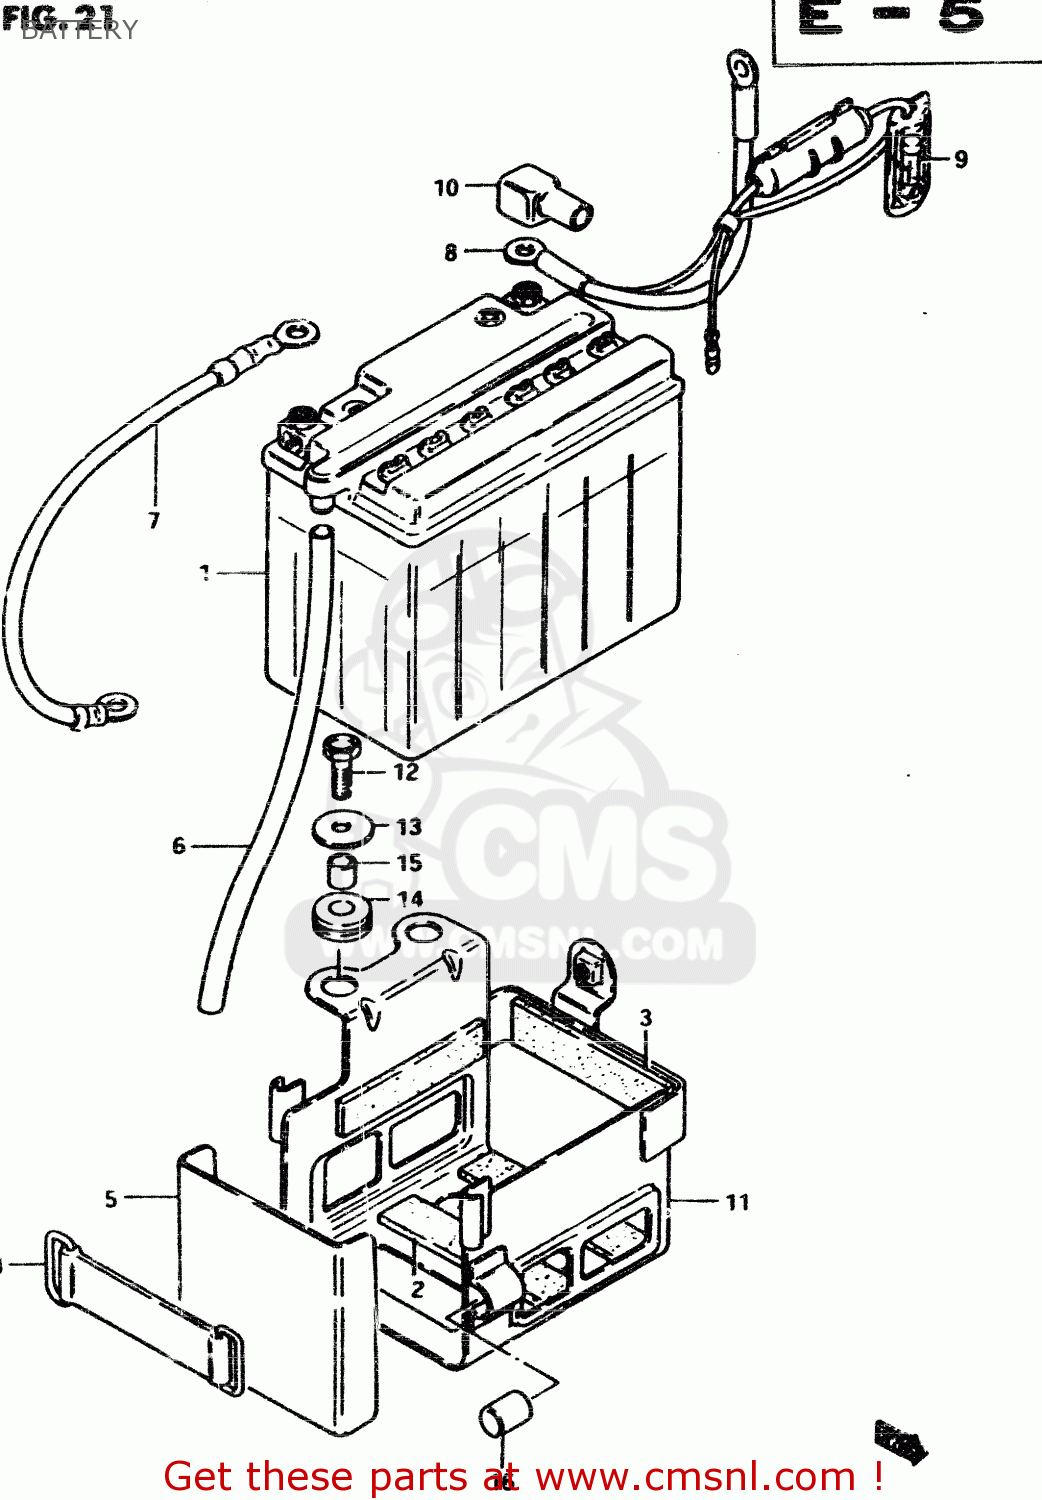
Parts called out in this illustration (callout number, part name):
1	BATTERY(YB12B-B2,12V11.6A)
2	CUSHION
3	PROTECTOR,20X9
4	BAND
5	COVER,BATTERY
6	HOSE,BATTERY EXHAUST
7	LEAD WIRE,BATTERY(-)
8	FUSE CASE AND PLUS CABLE
9	FUSE(15A)
10	CAP,TERMINAL
11	HOLDER,BATTERY
12	BOLT
13	WASHER
14	CUSHION
15	SPACER (6.1X9X9)
16	CUSHION
